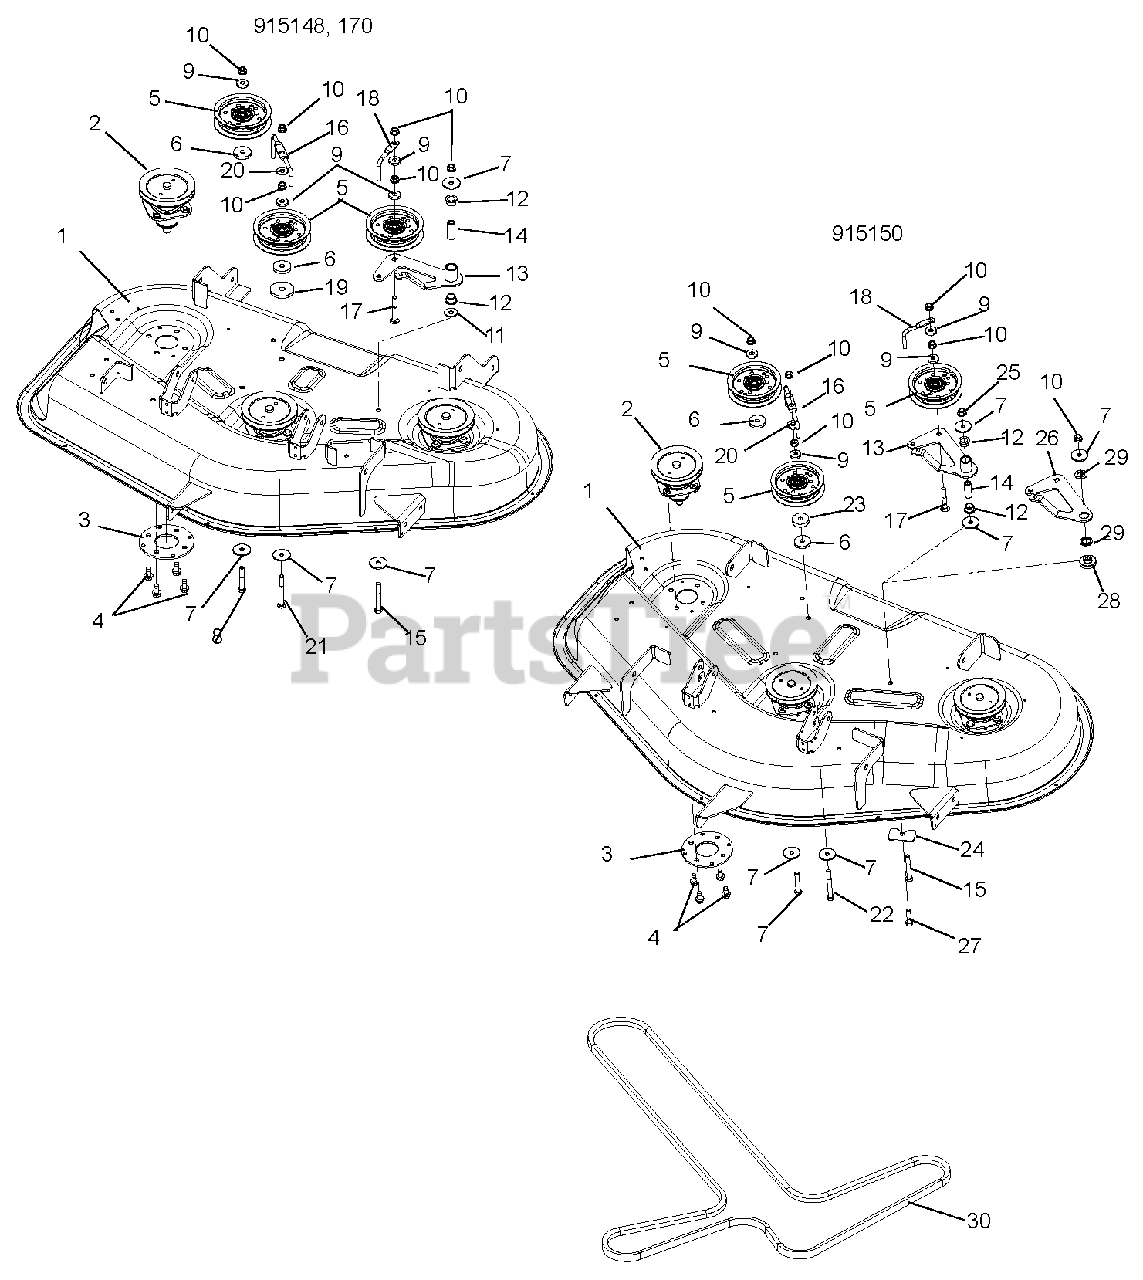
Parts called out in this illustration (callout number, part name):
1	Deck, 42" (915148, 170)
1	Deck, 50" (915150)
2	Assembly, Spindle (915148, 170)
2	Assembly, Spindle (915150)
3	Plate, Spindle
4	Screw, Tapping .38-16 x .75 Hex Washer Head
5	Assembly, Idler 4"
6	Washer, Flat, Steel .406 x 1.50 x .245
7	Washer, Flat, Steel .380 x 1.50 x .125
8	Bolt, Hex .38-16 x 2.25
9	Washer, Flat, Steel .406 x 1.00 x .188
10	Nut, Locking, Top, Flange .38-16
11	Washer, Flat, Steel .375 x 1.125 x .065
12	Bushing, Flange, .625 x .750 x .500 x 1.00
13	Weldment, Idler Arm
14	Spacer, .375ID x .625 OD x 1.66
15	Bolt, Hex .38-16 x 2.75
16	Belt Finger
17	Bolt, Round Head Square Neck .38-16 x 2.50
18	Wireform Belt Finger
19	Washer, Flat, Steel .469 x 2.00 x .25
20	Washer, Flat, Steel .438 x 1.00 x .083 (915148, 170)
21	Bolt, Hex .38-16 x 3.00 (915148, 170)
22	Bolt, Hex .38-16 x 3.25 (915150)
23	Spacer, .39 x 1.50 x .380 (915150)
24	Plate, Deck (915150)
25	Nut, Locking, Nylon, Flange .38-16 (915150)
26	Idler Arm (915150)
27	Bolt, Hex .38-16 x 1.50 (915150)
28	Spacer, Idler Arm (915150)
29	Bushing, Idler Arm (915150)
30	V-Belt, 4L Wrapped (915148, 170)
